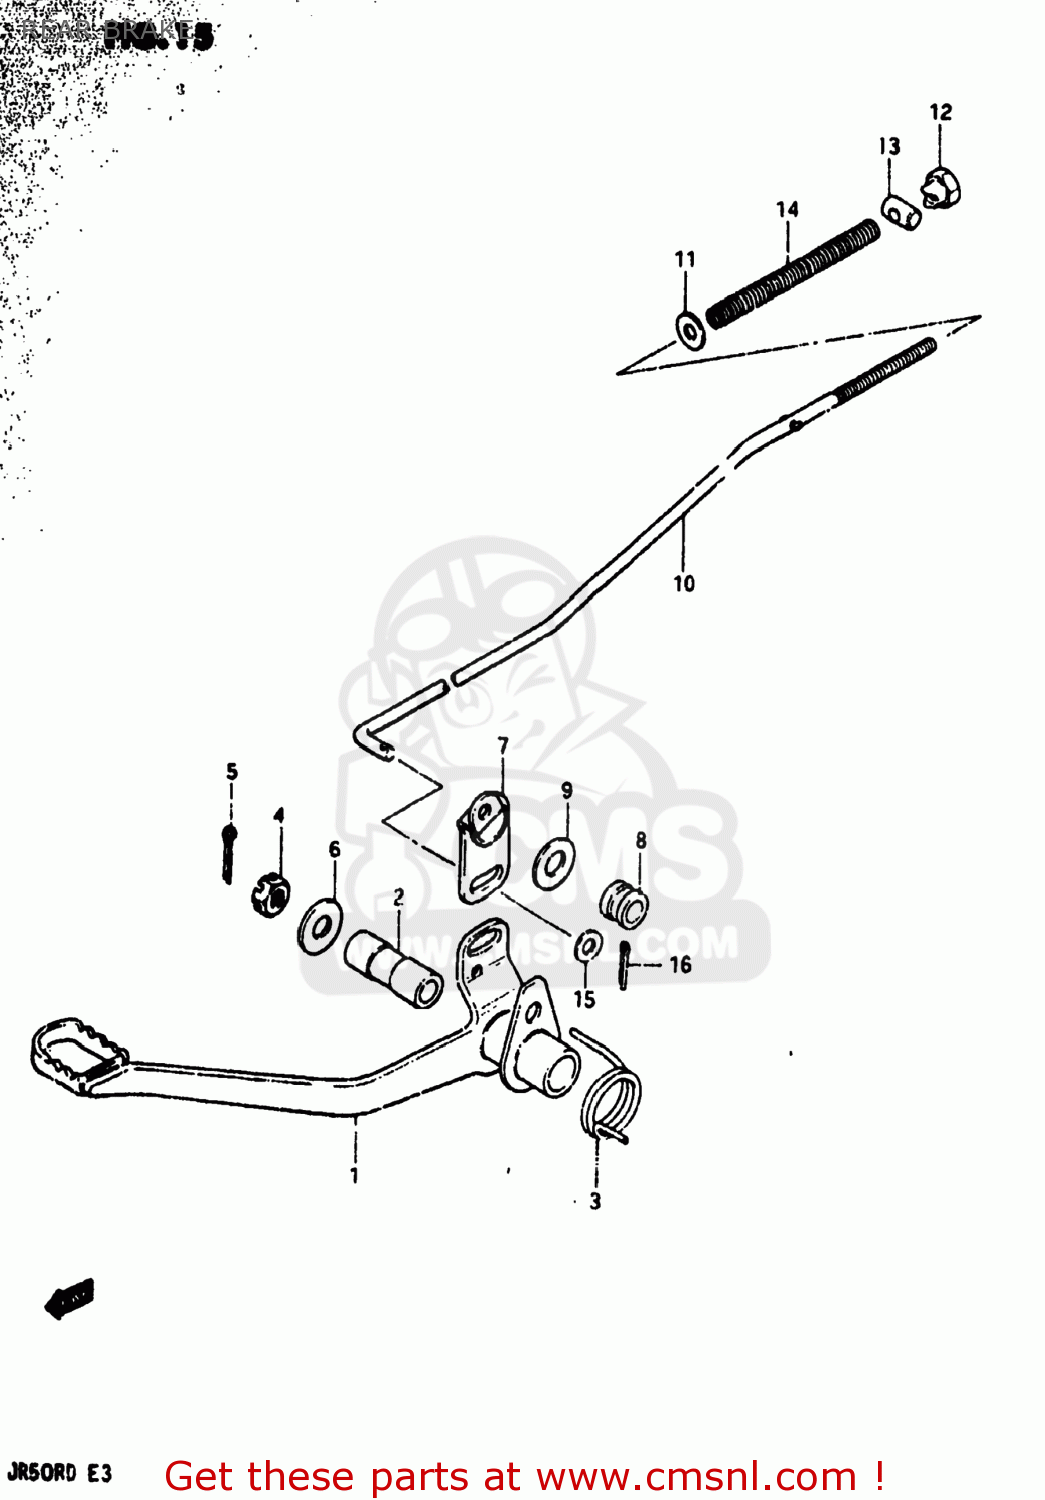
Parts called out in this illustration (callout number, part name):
1	PEDAL,BRAKE
2	SPACER,BRAKE PEDAL
3	SPRING,BRAKE PEDAL RETURN
4	NUT
5	PIN 25X20
6	WASHER
7	LEVER, SAFTY STARTER
8	SPACER,SAFTY STARTER
9	WASHER
10	ROD ASSEMBLY,REAR BRAKE
11	WASHER (5.5X16X1.2)
12	NUT
13	PIN,10X19
14	SPRING
15	WASHER
16	PIN 20X20
